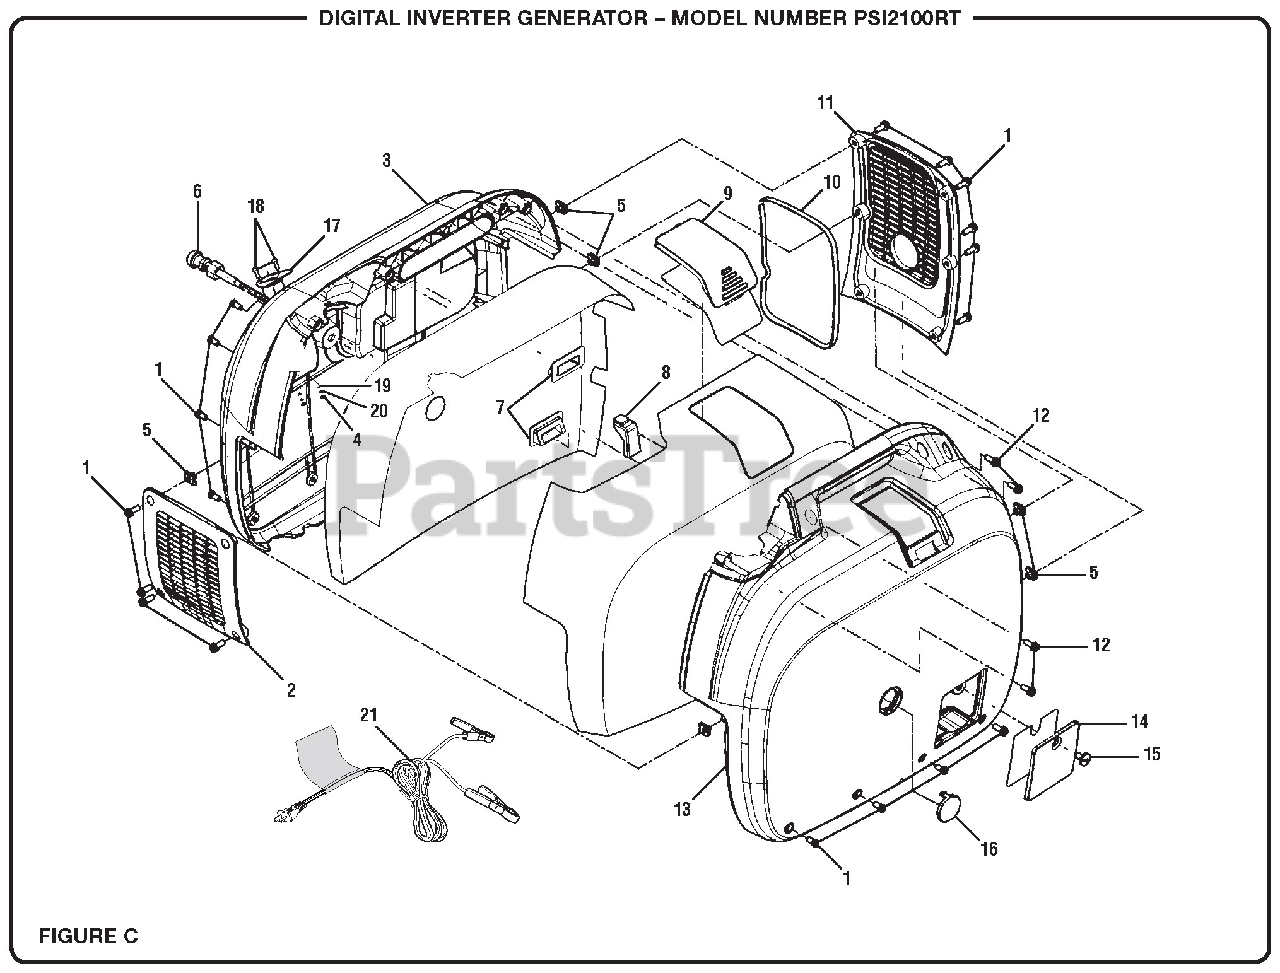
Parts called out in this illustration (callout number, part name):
1	Screw (M5 x 12 mm)
2	Air Intake Cover
3	Right Panel w/ Sound Foam
4	Hex Nut (M3)
5	U-Clip w/ Nut (M5)
9	Spark Plug Cover
11	Muffler Outer Cover
12	Screw (M5 x 15 mm)
13	Left Panel w/ Sound Foam
14	Oil Fill Cover
15	Bolt (M6 x 13 mm)
16	Fuel Drain Cover
17	Recoil Starter Bracket
18	Screw (M3 x 10 mm)
20	Spring Washer (M3)
21	DC Charging Cable
